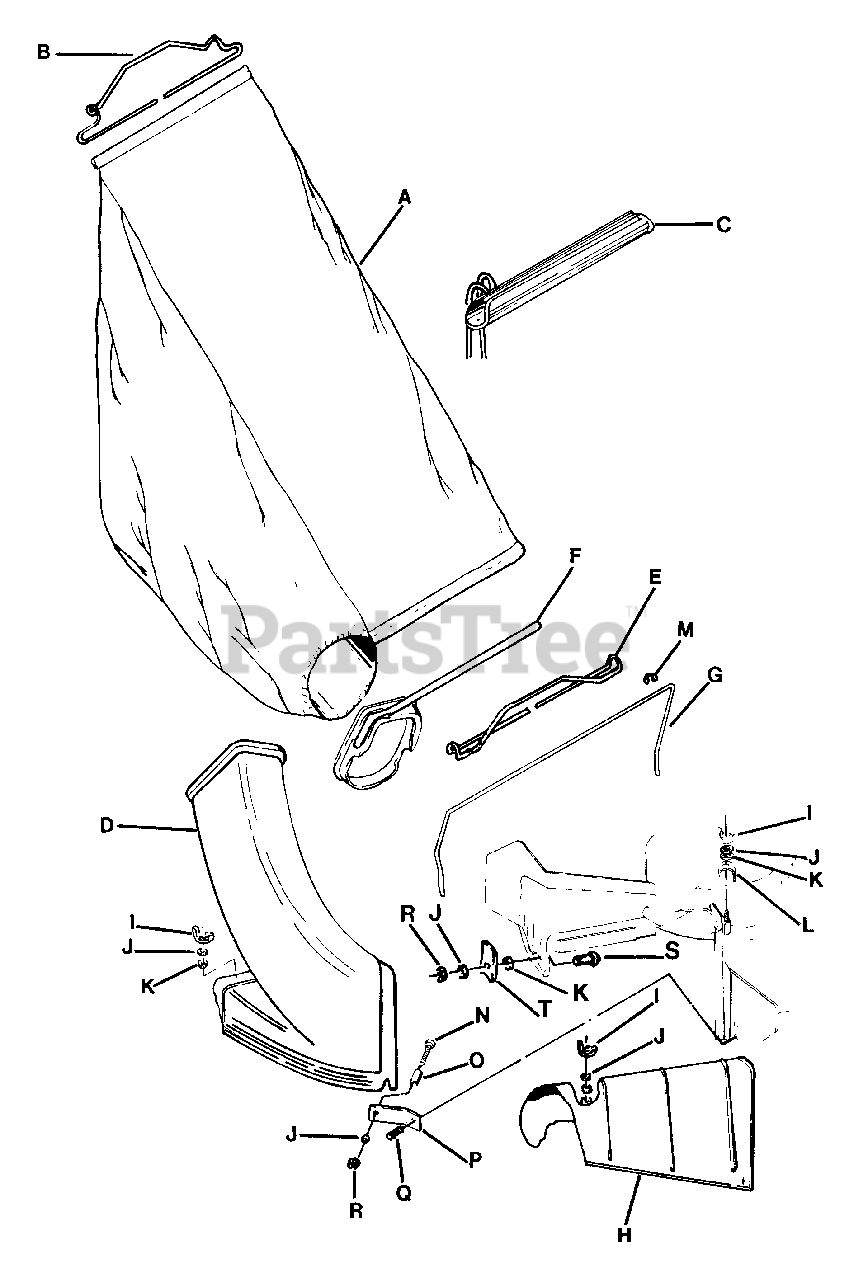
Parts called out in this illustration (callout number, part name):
A	BAG, Grass Catcher
B	WIRE, Bag Connector- Top
C	SLIDER, Bag Closure (Assembly)
D	ADAPTER, Bag V18
E	WIRE, Bag Connector
F	CONNECTOR, Bag
G	BAR, Bag Support Roll
H	CHUTE, Side (Structure)
I	NUT, 5/16-18 Wing
J	WASHER, 5/16" Split Lock
K	WASHER, 5/16" Flat
L	CLAMP, Adapter/Side Chute
M	RING, Nylon
N	SCREW, 5/16-18 x 1-1/4" Flat Head Machine
O	SPACER, Adapter or Side Chute
P	BRACKET, Side
Q	SCREW, 5/16-18 x 5/8" Self-Tapping SEMS
R	NUT, 5/16-18 Hex
S	BOLT, 5/16-18 x 1" Square Neck Carriage, Grade 5
T	GUIDE, Bracket
